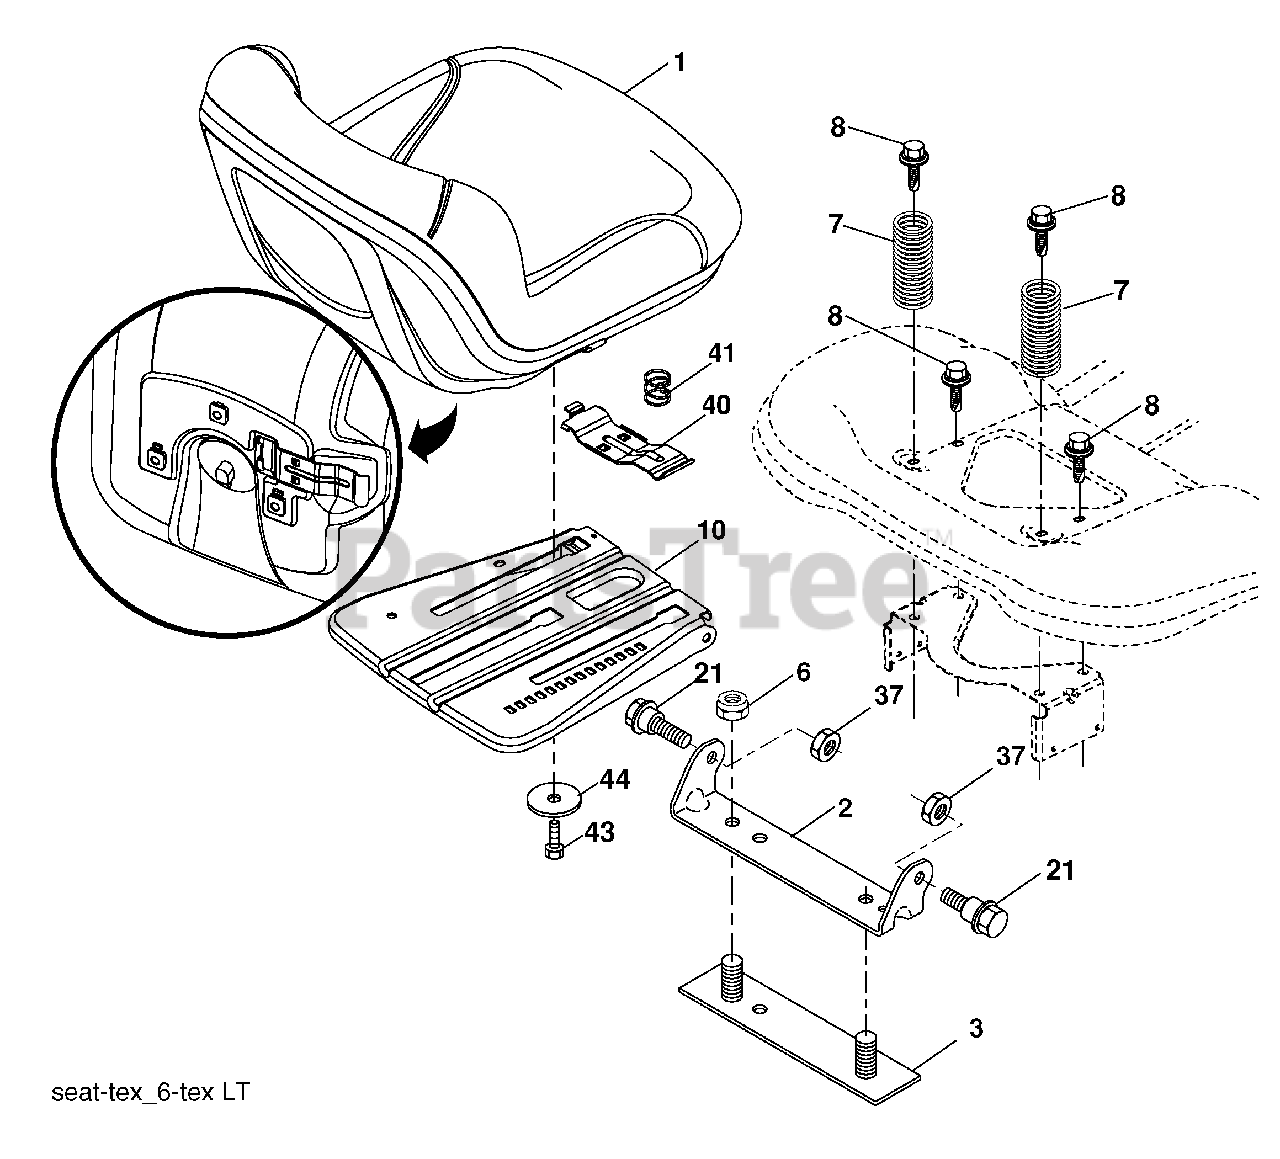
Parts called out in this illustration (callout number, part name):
1	Seat
2	Bracket Pivot Fender
3	Strap, Asm Fender
6	Nut, Lock w/Ins. 3/8-16 unc
7	Spring, Seat Cprsn
8	Bolt 5/16-18 unc x 3/4 w/Sems
10	Pan, Seat
21	Bolt, Shoulder 5/16-18
37	Nut, Lock 5/16-18 unc
40	Handle Slide Seat
41	Spring Latch Seat
43	Bolt Fin Hex 3/8-16 unc x 3/4
44	Washer 13/32 x 2-3/8 x 12 Ga.
